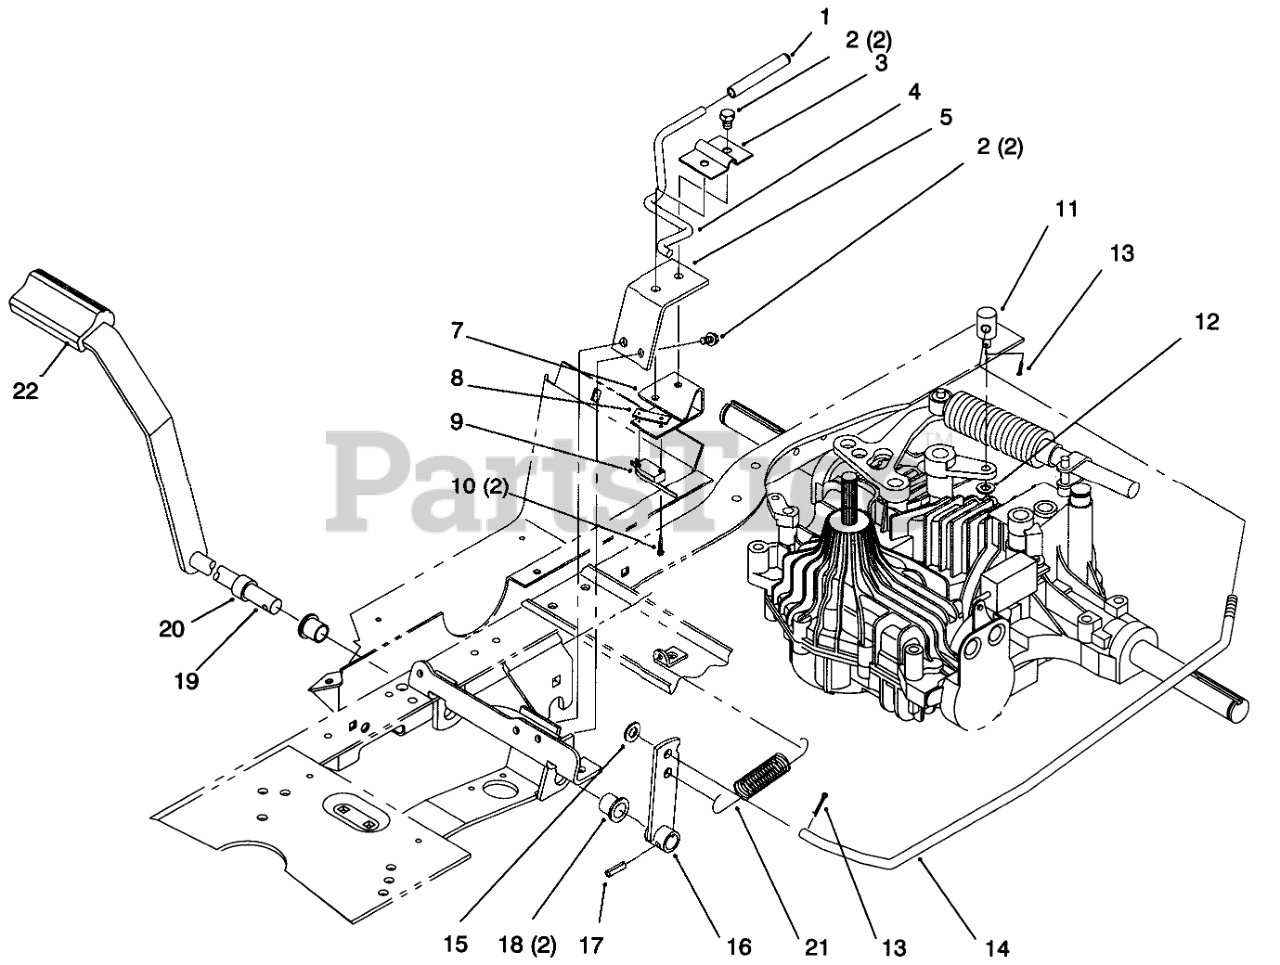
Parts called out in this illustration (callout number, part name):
1	Grip-Parking Brake (Only On: 72043, 72063, 72103)
2	Screw-HH (Only On: 72043, 72063, 72103)
3	Bracket-Park Brake (Only On: 72043, 72063, 72103)
4	Rod-Park Brake (Only On: 72043, 72063, 72103)
5	Support-Park Brake (Only On: 72043, 72063, 72103)
7	Bracket-Micro Sw (Only On: 72043, 72063)
8	Nut-Speed (Only On: 72043, 72063)
9	Switch-Micro (Only On: 72043, 72063)
10	Screw (Only On: 72043, 72063)
11	Trunnion-Brake (Only On: 72043, 72063, 72103)
12	Washer-Flat (Only On: 72043, 72063, 72103)
13	Pin-Cotter (Only On: 72043, 72063, 72103)
14	Rod-Brake (Only On: 72043, 72063, 72103)
15	Washer-Flat (Only On: 72043, 72063, 72103)
16	Lever-Brake (Only On: 72043, 72063, 72103)
17	Pin-Spring (Only On: 72043, 72063, 72103)
18	Bushing-Flange (Only On: 72043, 72063, 72103)
19	Pedal-Brake (Only On: 72043, 72063, 72103)
20	Spacer-Brake (Only On: 72043, 72063, 72103)
21	Spring-Extension (Only On: 72043, 72063, 72103)
22	Pad-Pedal (Only On: 72043, 72063, 72103)
